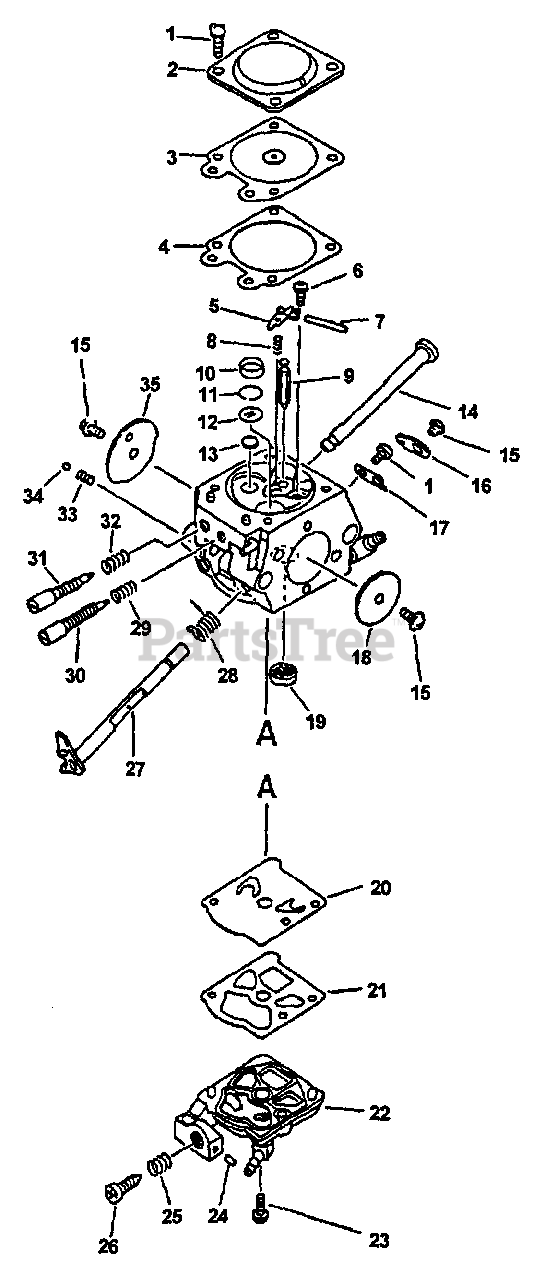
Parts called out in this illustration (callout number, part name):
1	REPAIR KIT
2	COVER, METERING
3	REPAIR KIT
3	DIAPHRAGM/GASKET KIT
4	GASKET, METERING
5	LEVER, METERING
6	SCREW, METERING LEVER PIN
7	PIN, METERING LEVER
8	SPRING, METERING LEVER
9	VALVE, INLET NEEDLE
10	PLUG, WELCH
11	RING, RETAINING
12	SCREEN, SPARK ARRESTOR
13	PLUG, WELCH
14	SHAFT, CHOKE
16	LEVER, THROTTLE
17	CLIP, THROTTLE SHAFT
18	VALVE, THROTTLE
19	STRAINER
20	DIAPHRAGM, PURGE
21	GASKET, PURGE
22	COVER, PUMP
23	SCREW, PUMP COVER
25	SPRING, IDLE ADJUST
26	SCREW, IDLE ADJUST
27	SHAFT, THROTTLE
28	SPRING, THROTTLE RETURN
29	SPRING, NEEDLE L.S.
30	NEEDLE - LOW SPEED
31	NEEDLE - HIGH SPEED
32	SPRING, NEEDLE H.S.
34	BALL, CHOKE
35	VALVE, CHOKE
